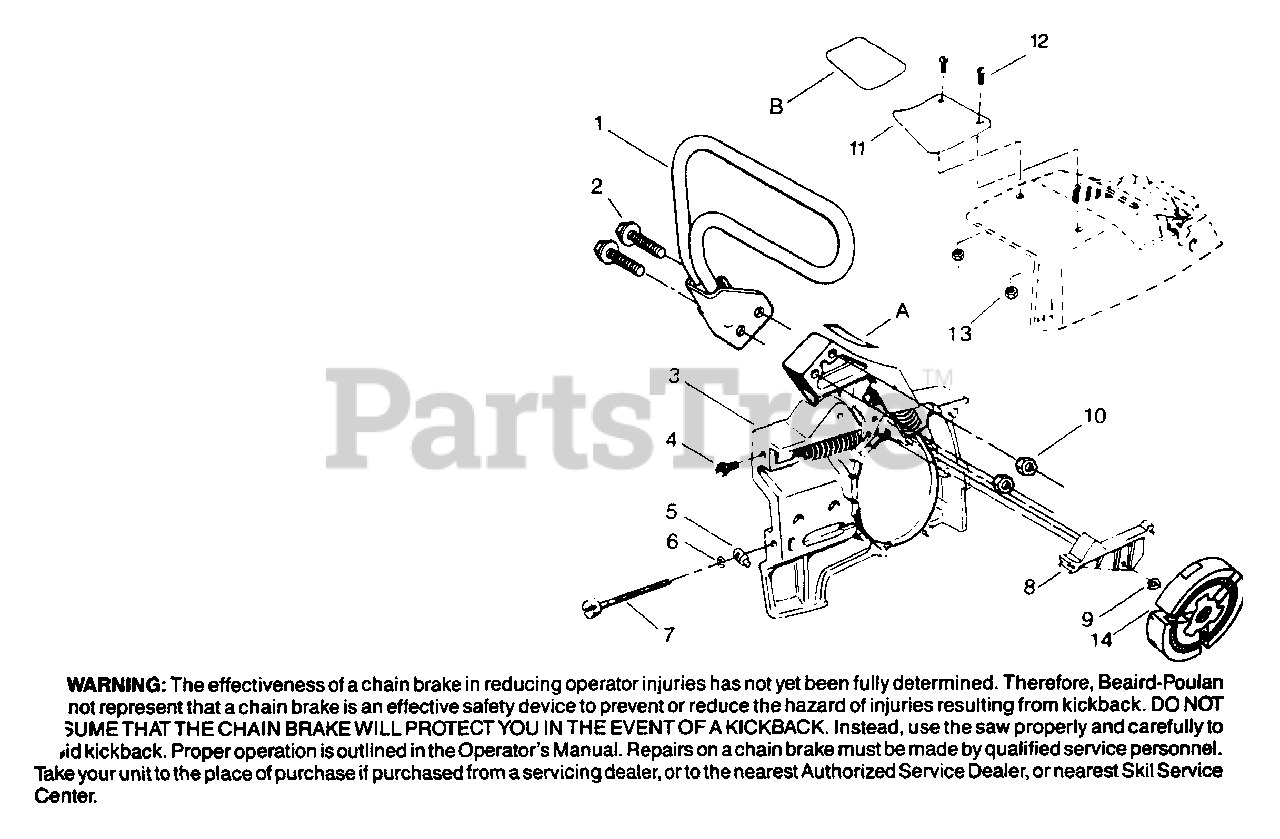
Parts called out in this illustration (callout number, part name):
1	Handle - Actuating Arm
2	Screw - Handle
3	Bar Clamp & Actuating Arm Ass'y.
4	Screw - Adjusting
5	Nut - Bar Adjusting
6	"E" Ring
7	Screw - Bar Adjusting
9	Retaining Ring
10	Nut - #10 - 24
11	Shield - Heat
12	Screw - #10 - 24 x 1/2
13	Nut - #10 - 24
A	Decal - Warning
B	Decal - Instruction (Heat Shield)
